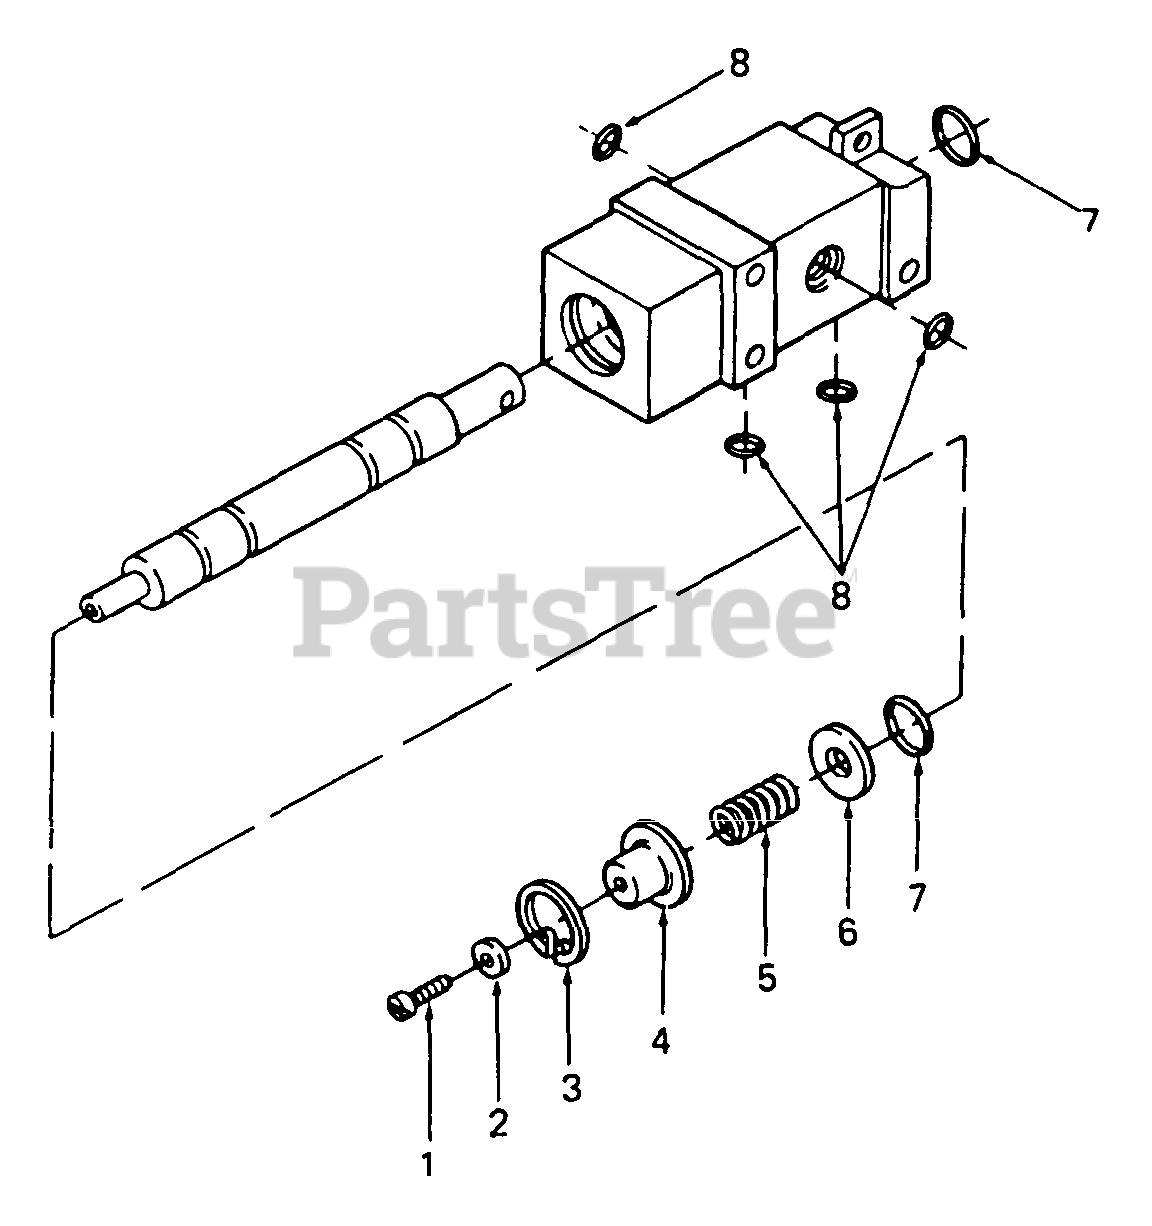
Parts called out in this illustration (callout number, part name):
1	Screw, Truss Mach, #10-24 x .38 Lg
2	Washer, Flat, .218 x .62 x .063 Thk
3	Ring, Int Snap, 1.023 Dia
4	Cup, Centering
5	Spring, Comp, .50 OD x .76 Lg
6	Washer, Flat, .344 x .75 x .105 Thk
7	O-Ring, .424 x .103 Dia
8	O-Ring, .301 x .070 Dia
